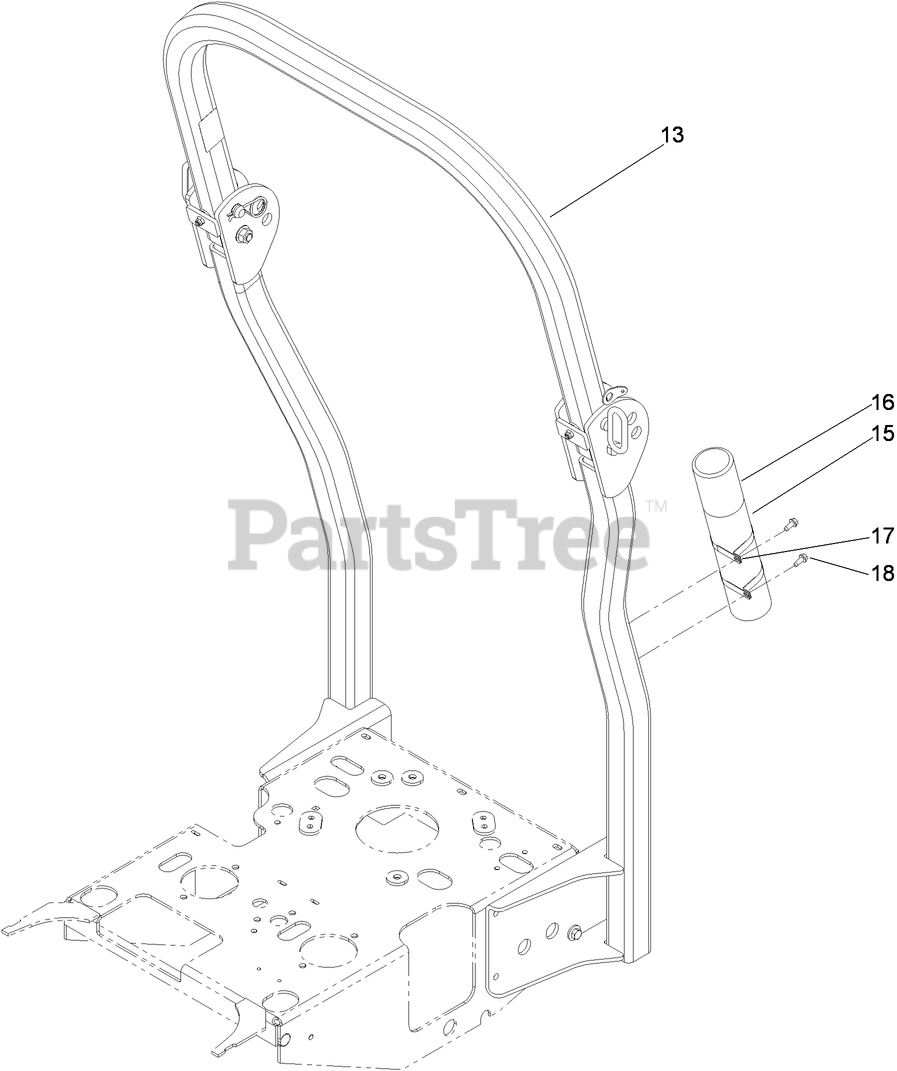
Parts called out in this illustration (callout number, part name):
13	ROPS KIT
15	TUBE-MANUAL
16	CAP-HOUSING
17	R-Clamp
18	SCREW-HWH
